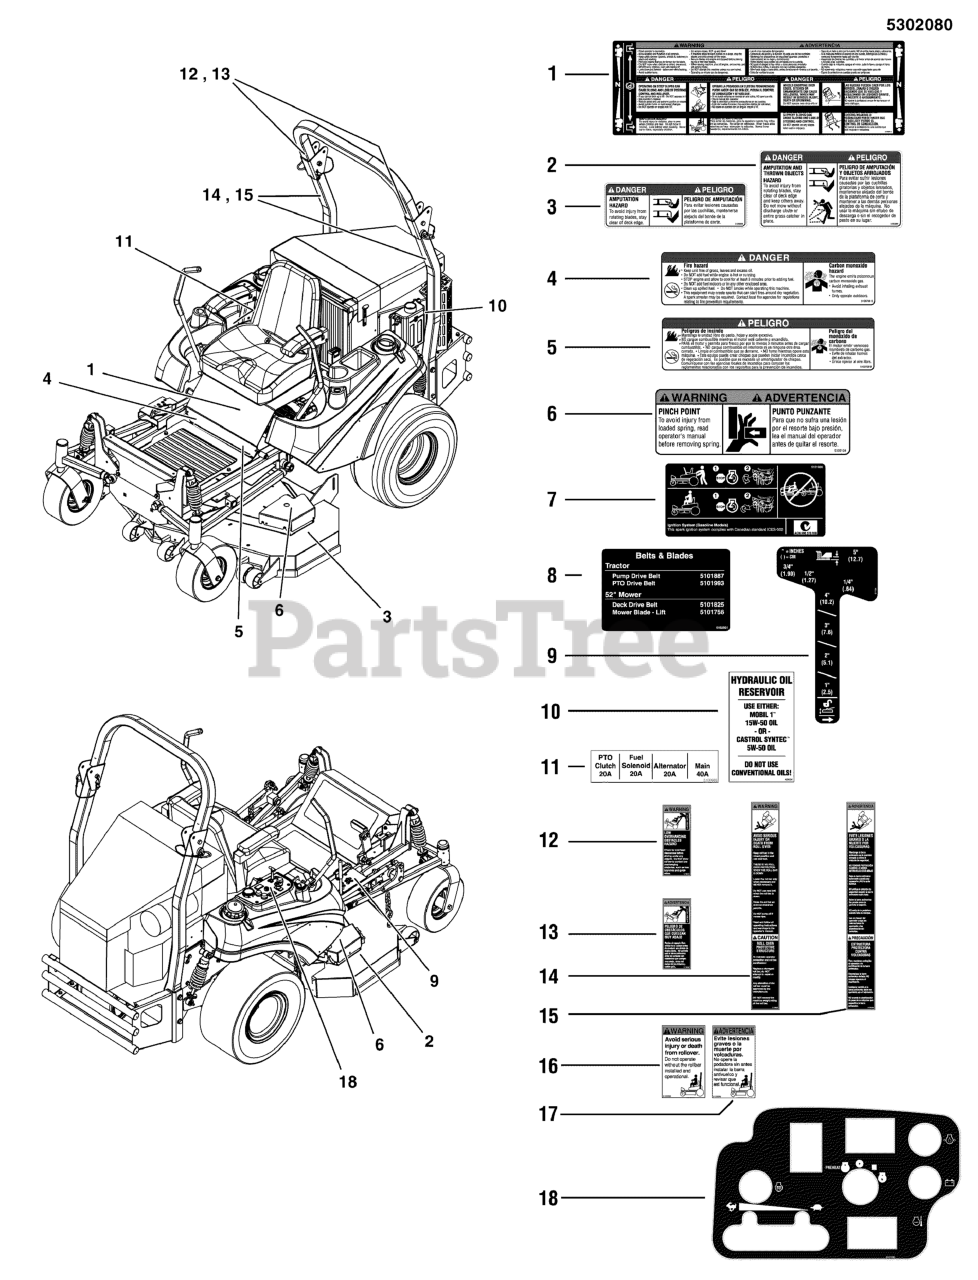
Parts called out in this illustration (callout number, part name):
1	DECAL, MAIN SAFETY
2	DECAL, DANGER, MOWER DISCHARGE,8.75X2.13
3	DECAL, DANGER, MOWER
4	DECAL, DANGER, FIRE
5	DECAL, DANGER, FIRE (SP)
6	DECAL, WARNING, PINCH POINT
7	DECAL, CZT HYRDO RELEASE
8	DECAL, BELT & BLADE, IS2500/S175X, DOM
9	DECAL-HEIGHT CITATION
10	DECAL, OIL RESEVOIR
11	DECAL, FUSE LOCATION
12	DECAL, WARNING
16	DECAL, WARNING, ROLL BAR
17	DECAL, WARNING, ROLL BAR, SP
18	DECAL, CONTROL PANEL, YANMAR
